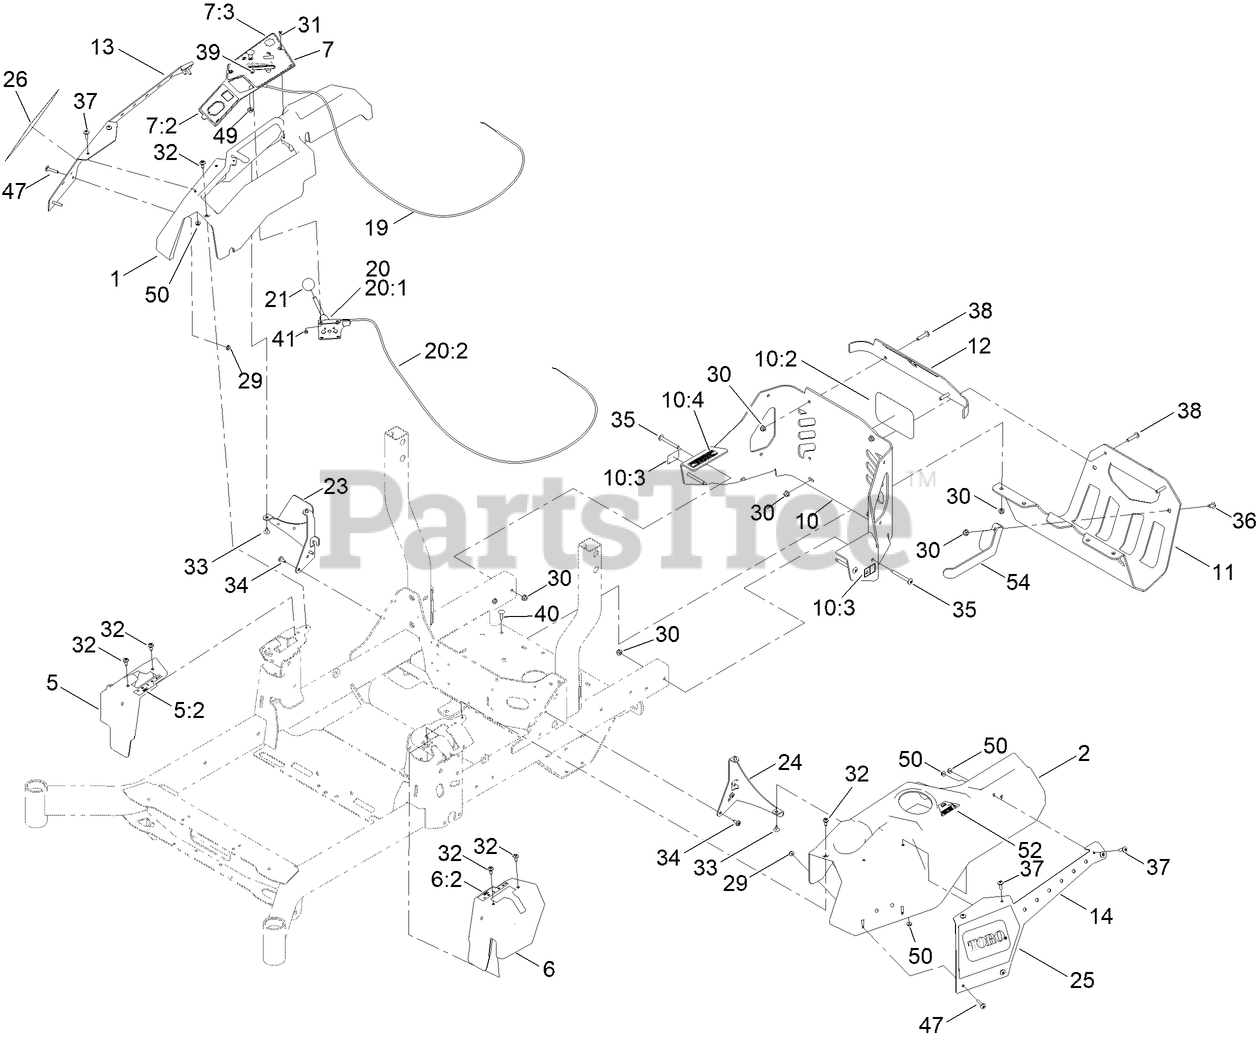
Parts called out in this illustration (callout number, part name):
1	CONSOLE-RH
2	CONSOLE-LH
5	COVER-CONTROL, MOTION (RH)
5:2	DECAL-CONTROL, MOTION (RH)
6	COVER-CONTROL, MOTION (LH)
6:2	DECAL-CONTROL, MOTION (LH)
7	CONTROL PANEL ASM
7:2	DECAL-PANEL, CONTROL
7:3	DECAL-PANEL, CONTROL
10	REAR GUARD ASM
10:2	DECAL
10:3	DECAL-WARNING
10:4	DECAL-ARRESTOR, SPARK
11	GUARD-MUFFLER [BLACK]
12	TRIM-UPPER REAR
13	COVER-POD, RH
14	COVER-LH
19	CABLE-CHOKE CONTROL
20	THROTTLE CONTROL ASM
20:1	LEVER-THROTTLE
21	KNOB-BALL
23	SUPPORT-CONSOLE, RH
24	BRACKET-CONSOLE, LH
25	DECAL-PLATE, LH
26	DECAL-PLATE, RH
29	NUT-HF
30	NUT-HF, NI
31	SCREW-HWH
32	SCREW-SHOULDER
33	SCREW-TORX
34	SCREW-TORX
35	SCREW-TORX
36	SCREW-TORX
37	SCREW-TRUSS
38	SCREW-TORX
39	BOLT-CARR
40	SCREW-CARR
41	NUT-LOCK, NI
47	SCREW-TRUSS
49	NUT-HJ
50	NUT-KEPS
52	DECAL-FILL, FUEL
54	BRACKET-GUARD, MUFFLER
